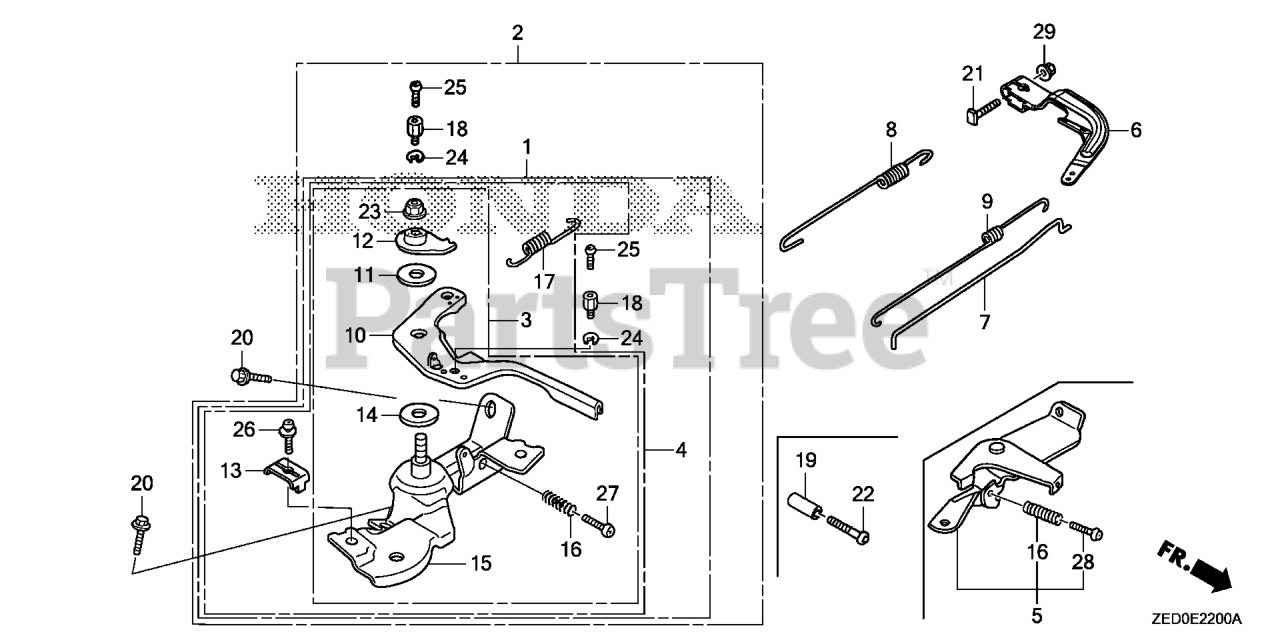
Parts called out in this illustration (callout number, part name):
4	CONTROL ASSY. (REMOTE)
6	ARM, GOVERNOR
7	ROD, GOVERNOR
8	SPRING, GOVERNOR
9	SPRING, THROTTLE RETURN
10	LEVER, CONTROL
11	SPRING, LEVER
12	WASHER, CONTROL LEVER
13	HOLDER, CABLE
14	SPACER, CONTROL LEVER
15	BASE, CONTROL (REMOTE)
15	BASE, CONTROL
16	SPRING, CONTROL ADJUSTING Use from Engine SN 2327377.
17	SPRING, CABLE RETURN
19	COLLAR, STOPPER
20	BOLT, FLANGE (6X12) (CT200)
21	BOLT, GOVERNOR ARM
22	SCREW, RECESSED (5X25)
23	NUT, SELF-LOCK (6MM)
26	SCREW, PAN (5X16)
27	SCREW, PAN (5X25)
29	NUT, FLANGE (6MM)
